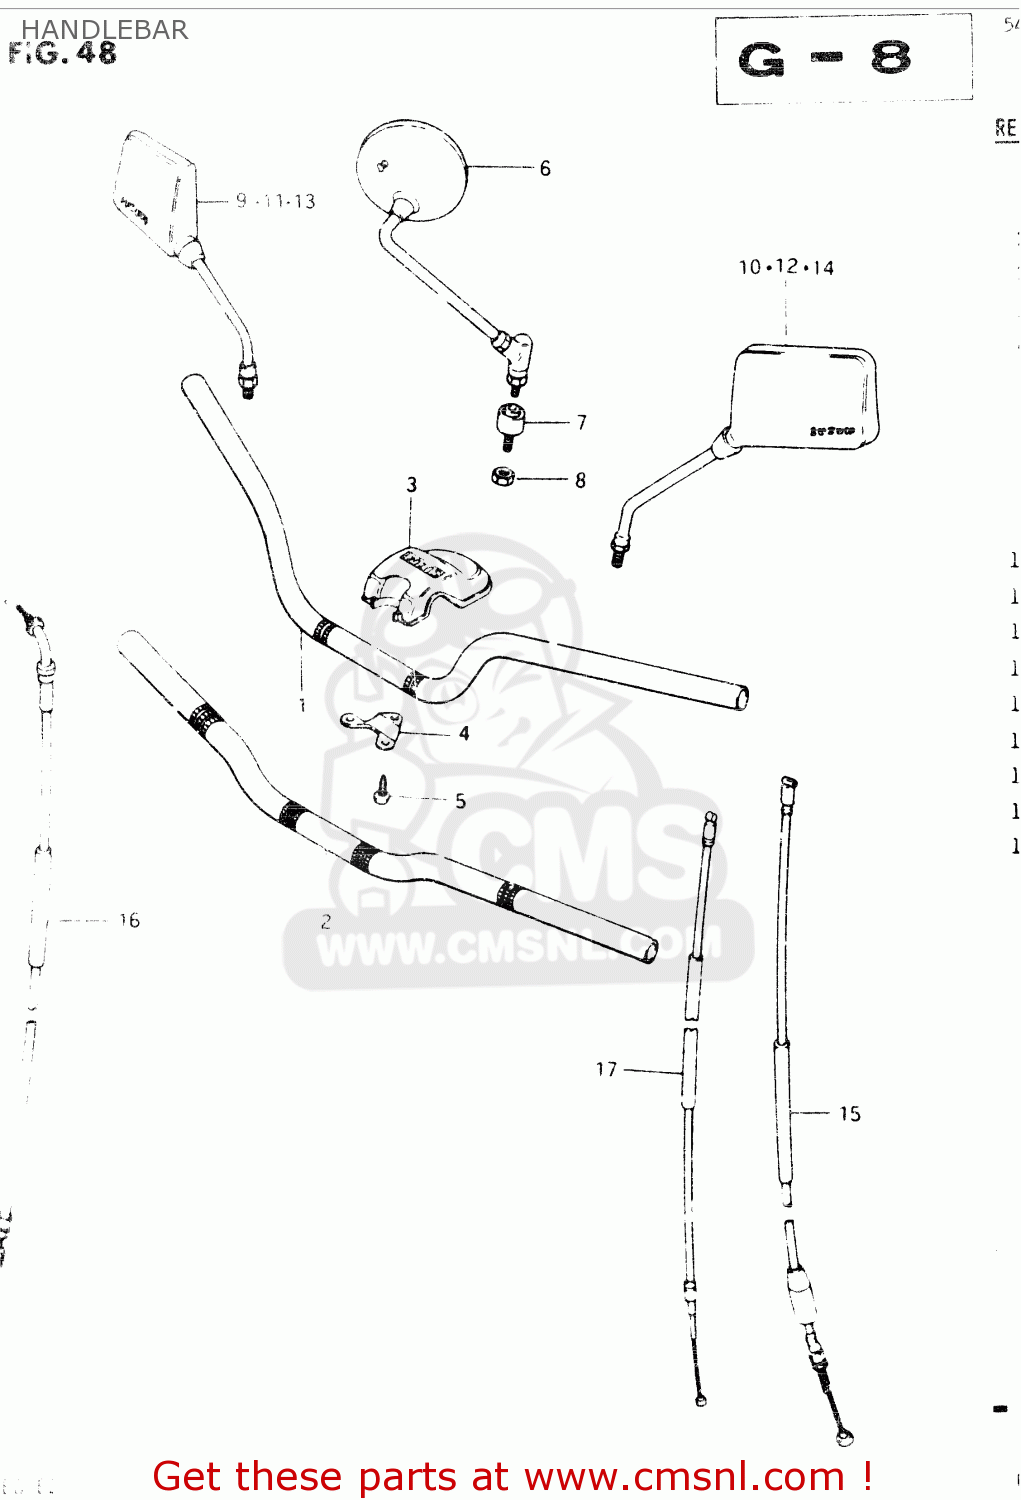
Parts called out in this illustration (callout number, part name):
1	HANDLEBAR
2	HANDLEBAR (FLAT HANDLEBAR)
3	COVER,STEERING HEAD
4	BRACKET,HEAD COVER
5	SCREW
6	MIRROR ASSY,RH
7	CUSHION,REAR VIEW MIRROR
8	NUT
9	MIRROR ASSEMBLY,REAR VIEW
10	MIRROR ASSEMBLY,REAR VIEW
11	MIRROR, REAR VIEW RH
12	MIRROR, REAR VIEW LH
13	MIRROR, REAR VIEW RH
14	MIRROR, REAR VIEW LH
15	CABLE ASSY,CLUTCH
16	CABLE ASSEMBLY,THROTTLE
17	CABLE, THROTTLE
